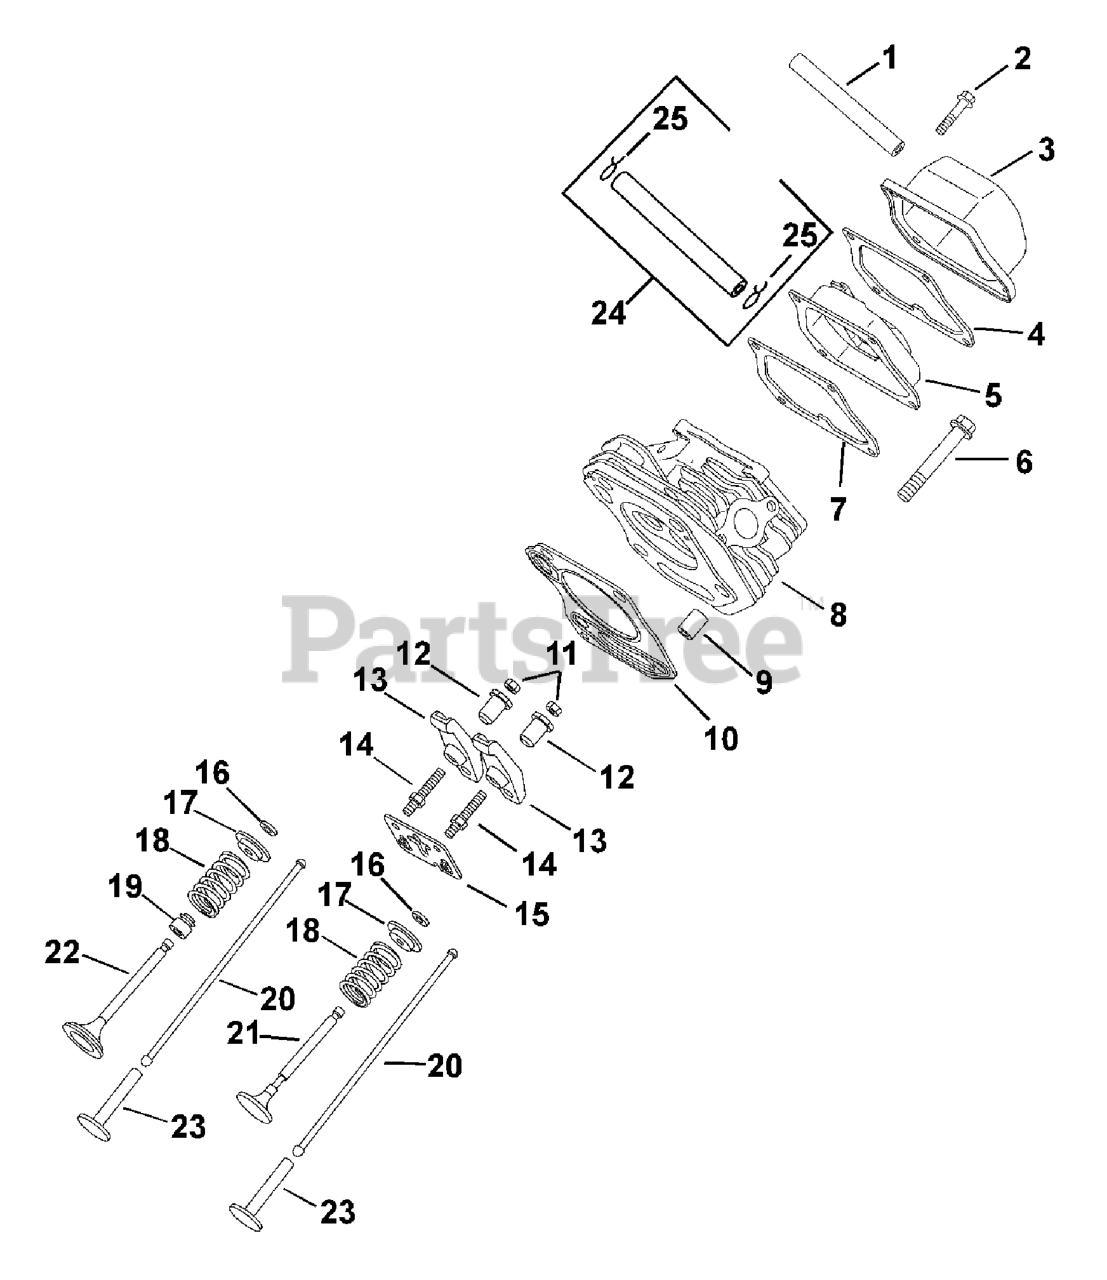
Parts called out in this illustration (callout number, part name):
1	HOSE, BREATHER 8.5 -USE 63 326 13-S
3	COVER, VALVE 8.5
4	GASKET, VALVE COVER
5	BREATHER ASSEMBLY 8.5
6	SCREW, CYL HEAD
7	GASKET, BREATHER 8.5
8	CYLINDER HEAD 8.5
9	PIN, DOWEL
10	GASKET, CYL HEAD 8.5
12	PIVOT, ROCKER ARM
13	ARM, ROCKER
14	SCREW, VALVE ADJ
15	PLATE, GUIDE
16	VALVE, COTTER-(#DSC)
17	CAP, VALVE SPRING
18	SPRING, VALVE
19	SEAL, VALVE STEM
21	VALVE, EXHAUST
22	VALVE, INTAKE
23	LIFTER, VALVE
